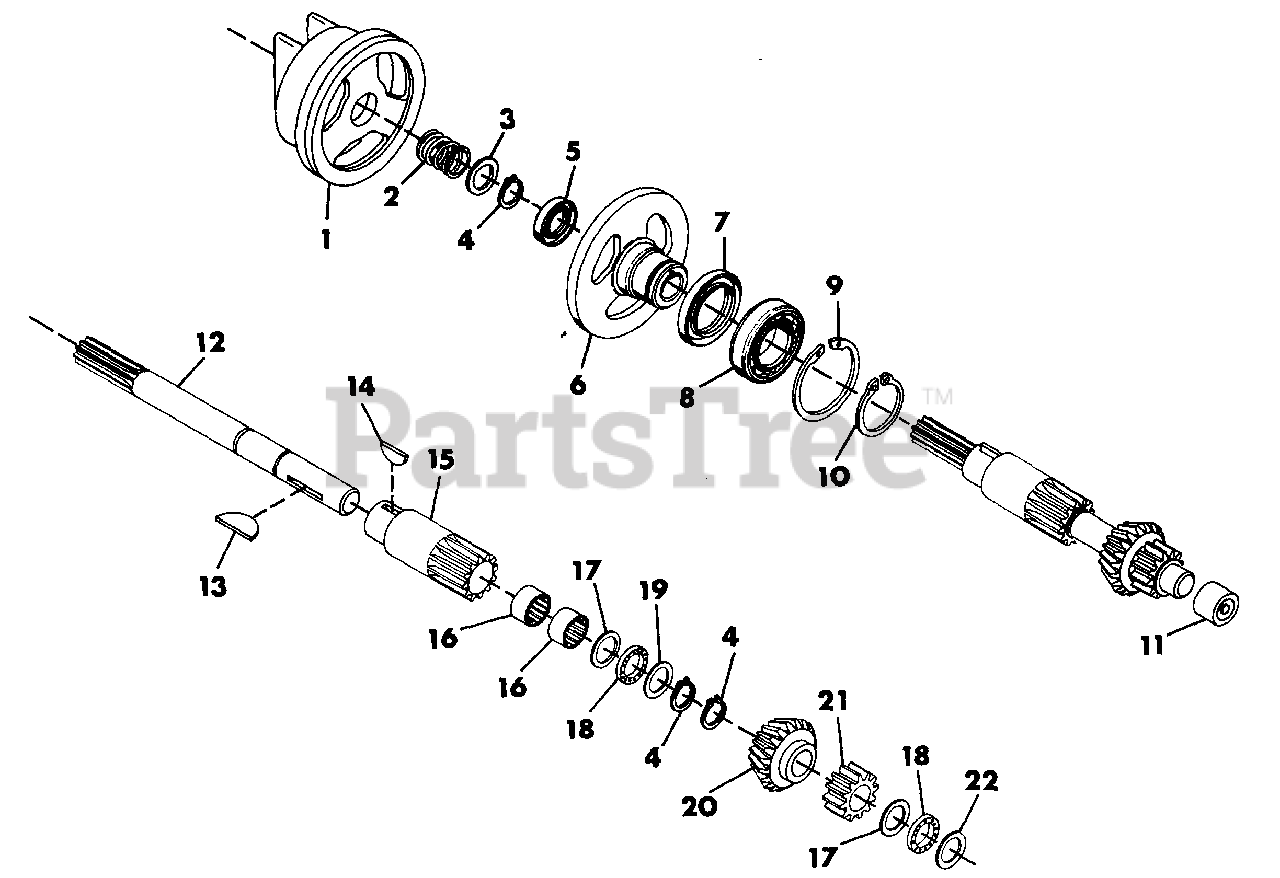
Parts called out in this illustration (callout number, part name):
1	NUMBER 11 - FWD-REV CLUTCH ASSEMBLY
2	SPRING, COMP. TYPE 1.0X.80X36 LB/IN
3	RACE, BEARING THRUST .752X1.240X.03
4	RING, RETAINING .750 SHAFT
5	SEAL, OIL .750X1.625X.250
6	HUB, CLUTCH
7	SEAL, OIL 2.250X3.005X.375
8	BEARING, BALL 1.968X3.149X.629
9	RING, RETAINING 3.156 BORE
10	RING, RETAINING 1.969 SHAFT
11	BEARING, NEEDLE .75X1.00X.75
12	SHAFT, SPLINED FORWARD CLUTCH
13	KEY, WOODRUFF .187X1.25 HARD #19
14	KEY, WOODRUFF .187X.625 HARD #61
15	GEAR
16	BEARING, NEEDLE .75X1.00X.50
17	RACE, BEARING THRUST
18	BEARING, NEEDLE THRUST
19	RACE, BEARING THRUST .060
20	GEAR, BEVEL
21	GEAR, 10 DP 16 TEETH X.750
22	RACE, BEARING THRUST
